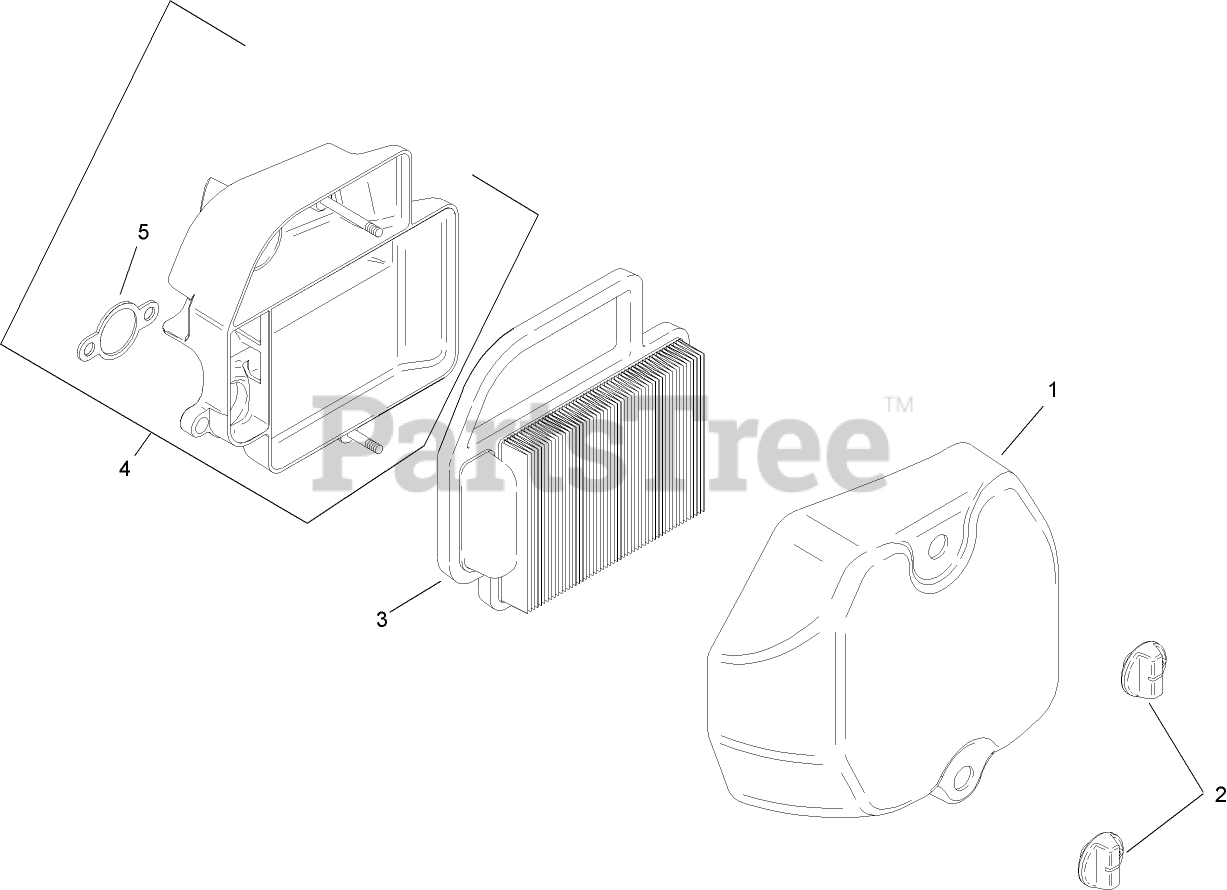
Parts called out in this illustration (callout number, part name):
1	AIR CLEANER COVER ASM
2	KNOB-COVER
3	FILTER-AIR
4	Air Cleaner Base Kit (Includes 5)
5	Gasket-Base, Air Cleaner
